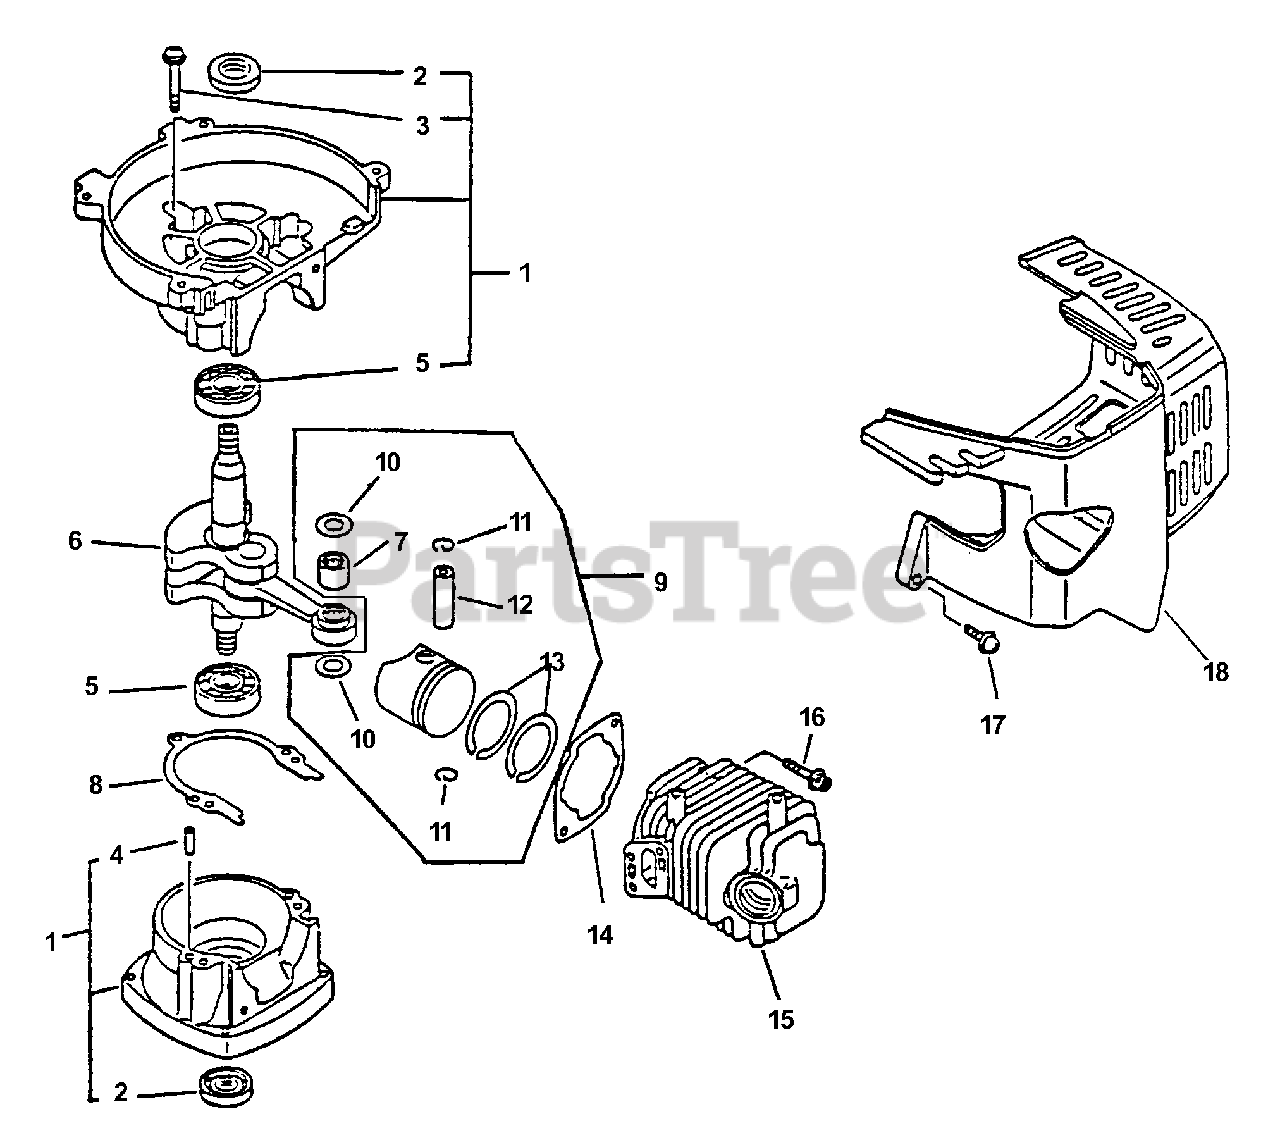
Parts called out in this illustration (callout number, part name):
1	CRANKCASE KIT
2	SEAL, OIL
3	SCREW - 5X28
4	PIN - LOCATING
5	BEARING, BALL - 6201
6	CRANKSHAFT ASSY
7	BEARING, NEEDLE
7	BEARING, NEEDLE - 8
8	GASKET, CRANKCASE
9	PISTON KIT
10	SPACER, PISTON
10	WASHER
11	RING, RETAINING
12	PIN, PISTON
13	RING, PISTON
14	GASKET, CYLINDER
15	CYLINDER
16	SCREW - 5X22
17	SCREW - 4X22
18	COVER, ENGINE
